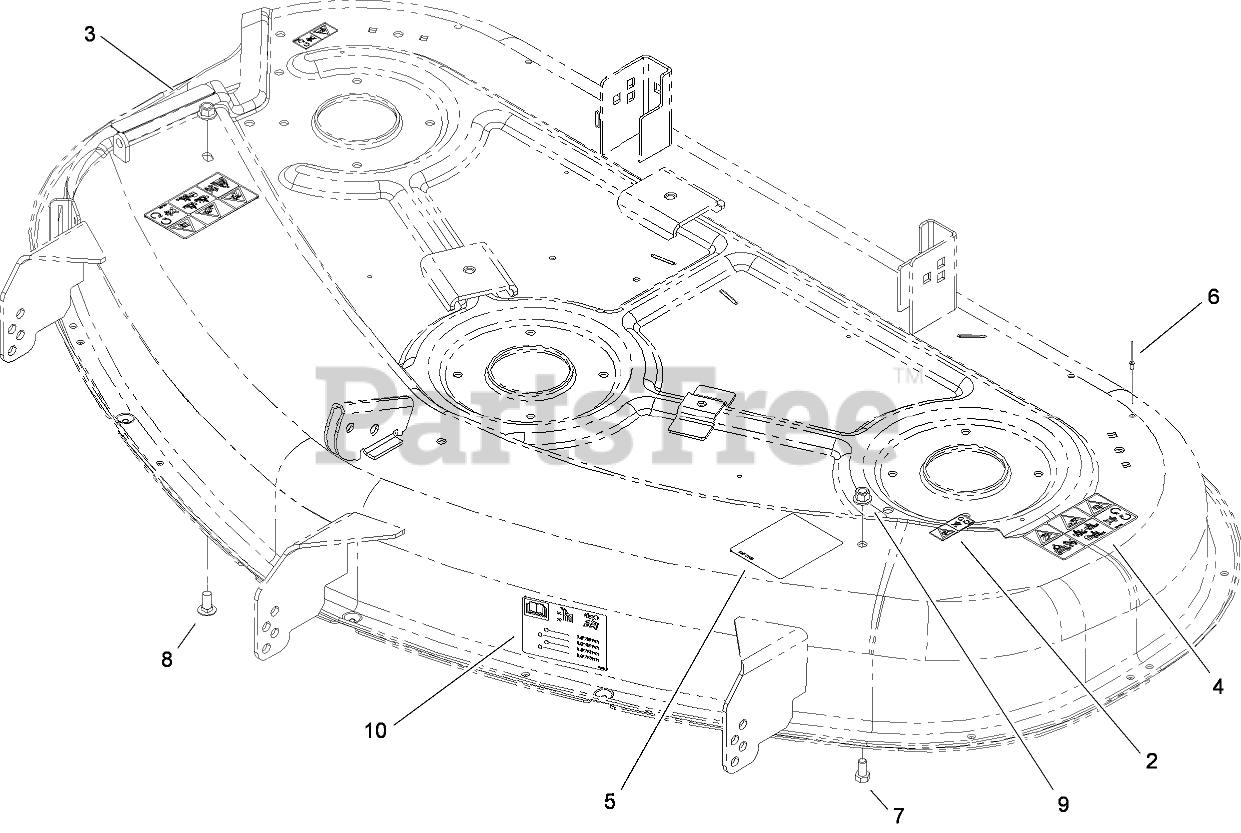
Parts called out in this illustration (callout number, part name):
2	DECAL-DANGER
3	DECAL-DANGER
4	DECAL-DANGER
5	DECAL-ROUTING, BELT
6	RIVET-BLIND
7	SCREW-HH
8	SCREW-CARR
9	NUT-HF, NI
10	DECAL-SCALP, ANTI
